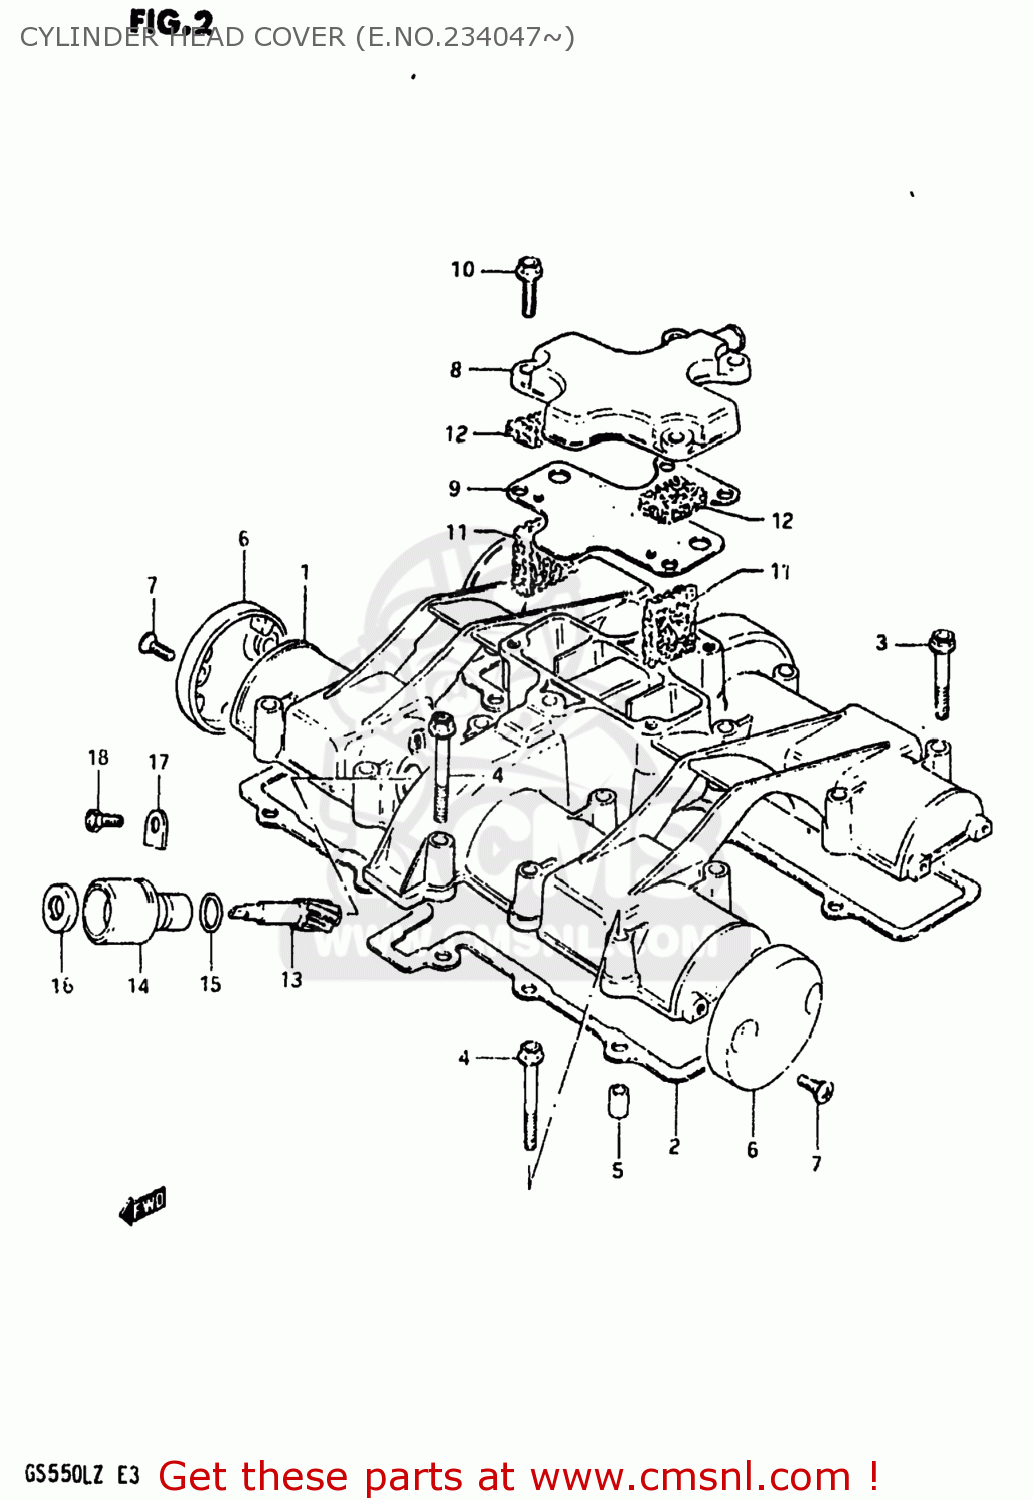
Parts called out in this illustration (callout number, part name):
1	COVER,CYLINDER HEAD
2	GASKET,CYLINDER HEAD COVER (MCA)
3	BOLT
4	BOLT,UNDER
5	PIN(6.2X8X11)
6	CAP,CYLINDER HEAD COVER
7	SCREW(5X12)
8	COVER,BREATHER
9	GASKET (MCA)
10	BOLT,REAR
11	COVER,BREATHER
12	SEPARATOR,OIL BREATHER
13	GEAR,TACHOMETER DRIVEN
14	SLEEVE,TACHOMETER DRIVE
15	SEAL,TACHOMETER DRIVEN
16	SEAL,OIL(5X12X8)
17	PLATE,TACH DRIVE GEAR SLEEVE
18	SCREW(5X12)
